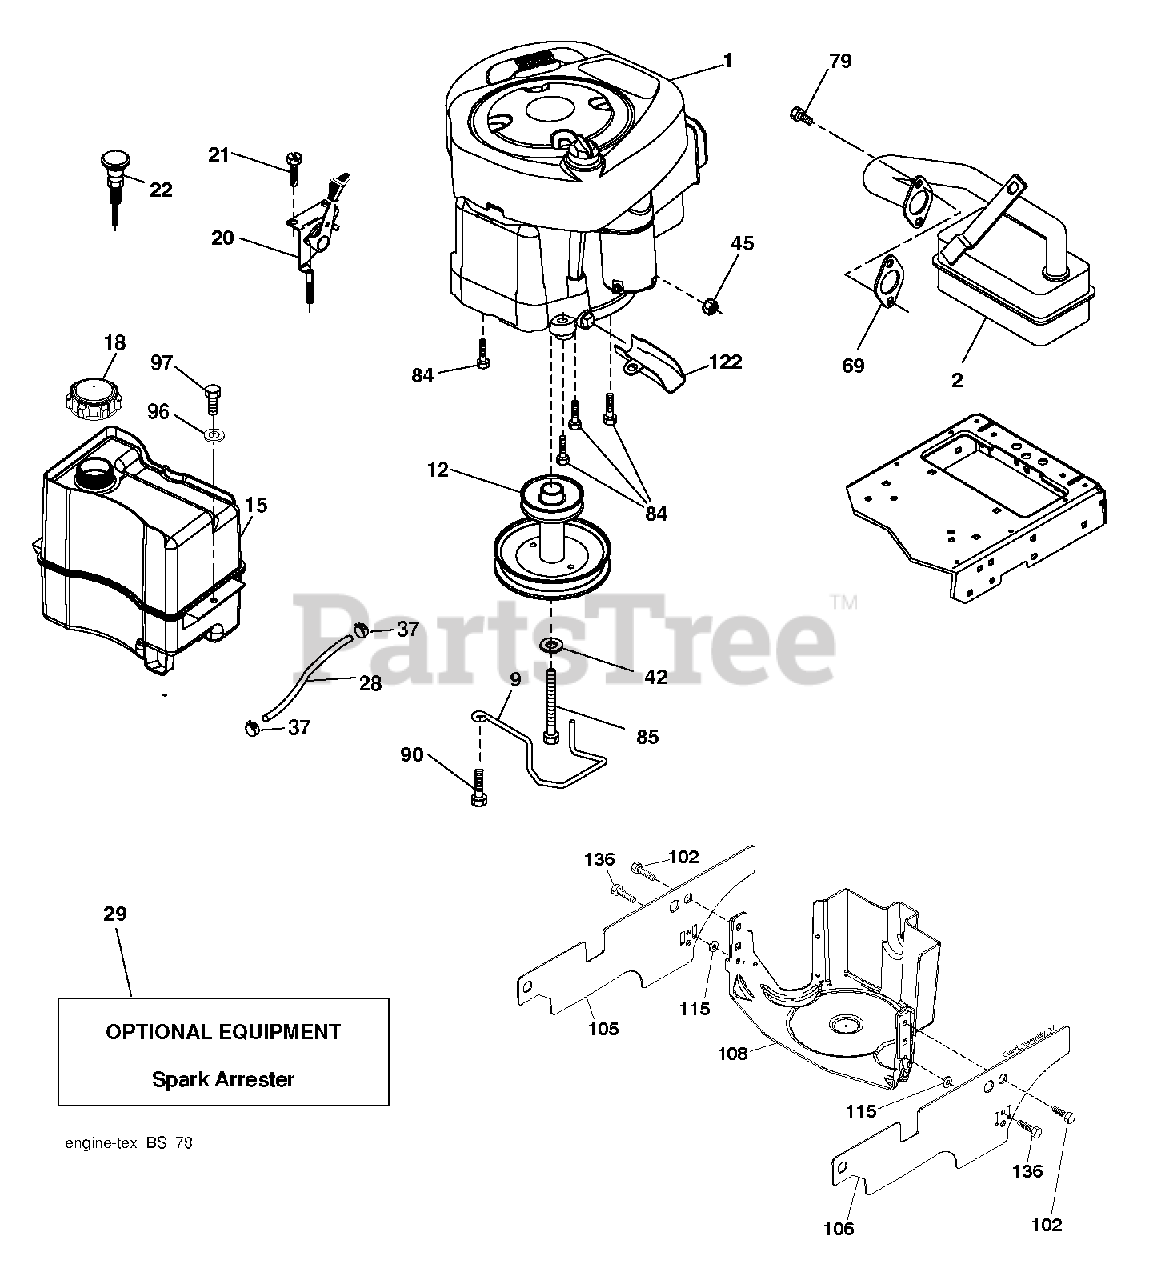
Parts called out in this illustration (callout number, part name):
9	Belt Keeper, 4 25"2 Blt 431
12	PULLY ENGINE
18	CAP ASM.FUEL.2.25"FR.
20	CONTROL.TH/CK.C.
21	SCREW.#10 X 0.750.BOS THREAD
28	LINE.FUEL.20
29	ARRESTER SPARK (OPTIONAL)
37	HOSE CLAMP
42	LOCKWASHER
45	NUT
69	REPL BY 532 27 22-93
79	SCREW.SOCKET HD.5/16-1
84	SCREW.3/8-16
85	BOLT HEX 7/16-20X4-1/4"
90	SCREW 3/8-16X1
97	SCREW HEXWSHR 1/4-20X3/4
102	SCREW
115	PALNUT 1/4
122	EXTENSION DRAIN OIL
136	SCREW.1/4-20X5/8
